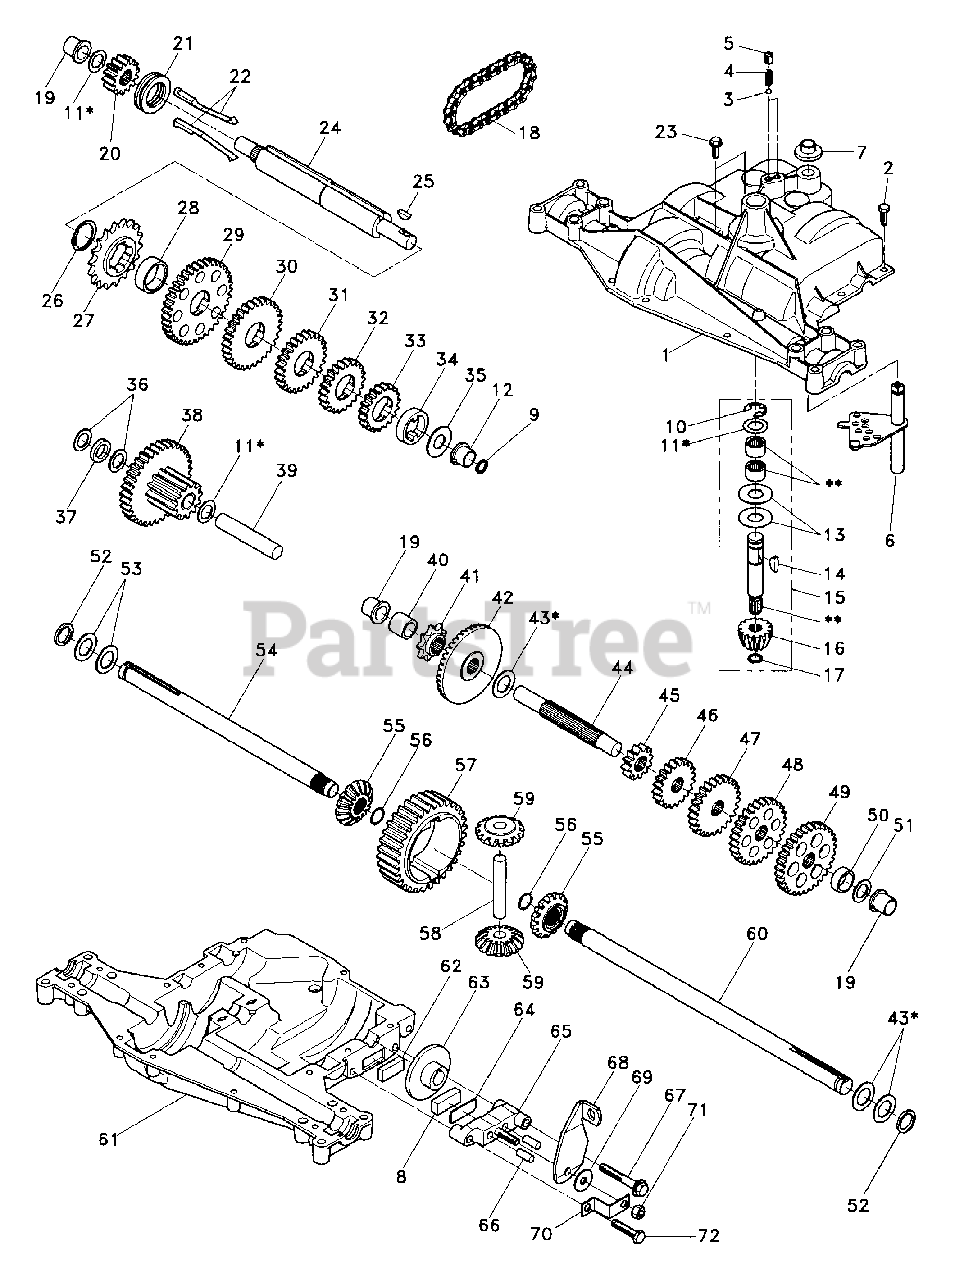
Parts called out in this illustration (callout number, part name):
1	Housing, Upper
2	Screw, Self-Tapping, Large 1/4-20 x .734
3	Ball, Detent
4	Spring, Detent
5	Screw, Set
6	Kit, Shifter Assembly
7	Boot, Shifter
8	Puck, Friction
9	Seal, Oil
10	Ring, Retaining
11	Assembly, Kit, Shim .625 Shaft
12	Bearing, Flange
13	Washer, Plain .632 x 1.38 x .046
14	Key, Woodruff, #9
15	Assembly, Kit, Input Shaft
16	Pinion, Bevel, 14 Teeth
17	Ring, Retaining
18	Chain, 24 Pitches
19	Bearing, Flange
20	Gear, Spur, 14 Teeth
21	Collar, Clutch
22	Assembly, Kit, Clutch Keys
23	Screw, Self-Tapping, with Sealer
24	Shaft, Intermediate
25	Key, Woodruff, #61
26	Ring, Retaining
27	Sprocket, 18 Teeth (Reverse)
29	Gear, Spur, 37 Teeth (1(st))
30	Gear, Spur, 30 Teeth (2(nd))
31	Gear, Spur, 25 Teeth (3(rd))
32	Gear, Spur, 22 Teeth (4(th))
33	Gear, Spur, 19 Teeth (5(th))
34	Spacer 1.133 x 1.50 x .375
35	Washer, Plain .640 x 1.37 x .061
36	Washer, Plain .632 x 1.00 x .026
37	Spacer .630 x 1.00 x .169
38	Assembly, Gear, Combination of 12 Teeth and 35 Teeth
39	Shaft, Idler
40	Spacer .635 x .875 x .755
41	Sprocket, 9 Teeth (Reverse)
42	Gear, Bevel, 42 Teeth
43	Assembly, Kit, Shim .750 Shaft
44	Shaft, Drive
45	Gear, Spur, 12 Teeth (1(st))
46	Gear, Spur, 20 Teeth (2(nd))
47	Gear, Spur, 25 Teeth (3(rd))
48	Gear, Spur, 28 Teeth (4(th))
49	Gear, Spur, 31 Teeth (5(th))
50	Spacer .781 x 1.00 x .375
51	Washer, Plain .632 x 1.00 x .060
52	Washer, Neoprene
53	Washer, Plain .758 x 1.25 x .031
54	Axle, L.H.
55	Gear, Miter, 15 Teeth
56	Ring, Retaining
57	Gear, Spur, 32 Teeth
58	Shaft, Cross
59	Gear, Miter, 15 Teeth
60	Axle, R.H.
61	Housing, Lower
62	Puck, Friction
63	Disc, Brake
65	Jaw, Brake
66	Pin, Dowel
67	Screw, Self-Tapping, Large 5/16-18 x 2.25
68	Lever, Actuating
69	Washer, Plain .321 x 1.00 x .055
70	Bracket, Anti-Rotation
71	Locknut 5/16-24
72	Screw, Self-Tapping, Large 5/16-18 x 1.44
73	Grease
